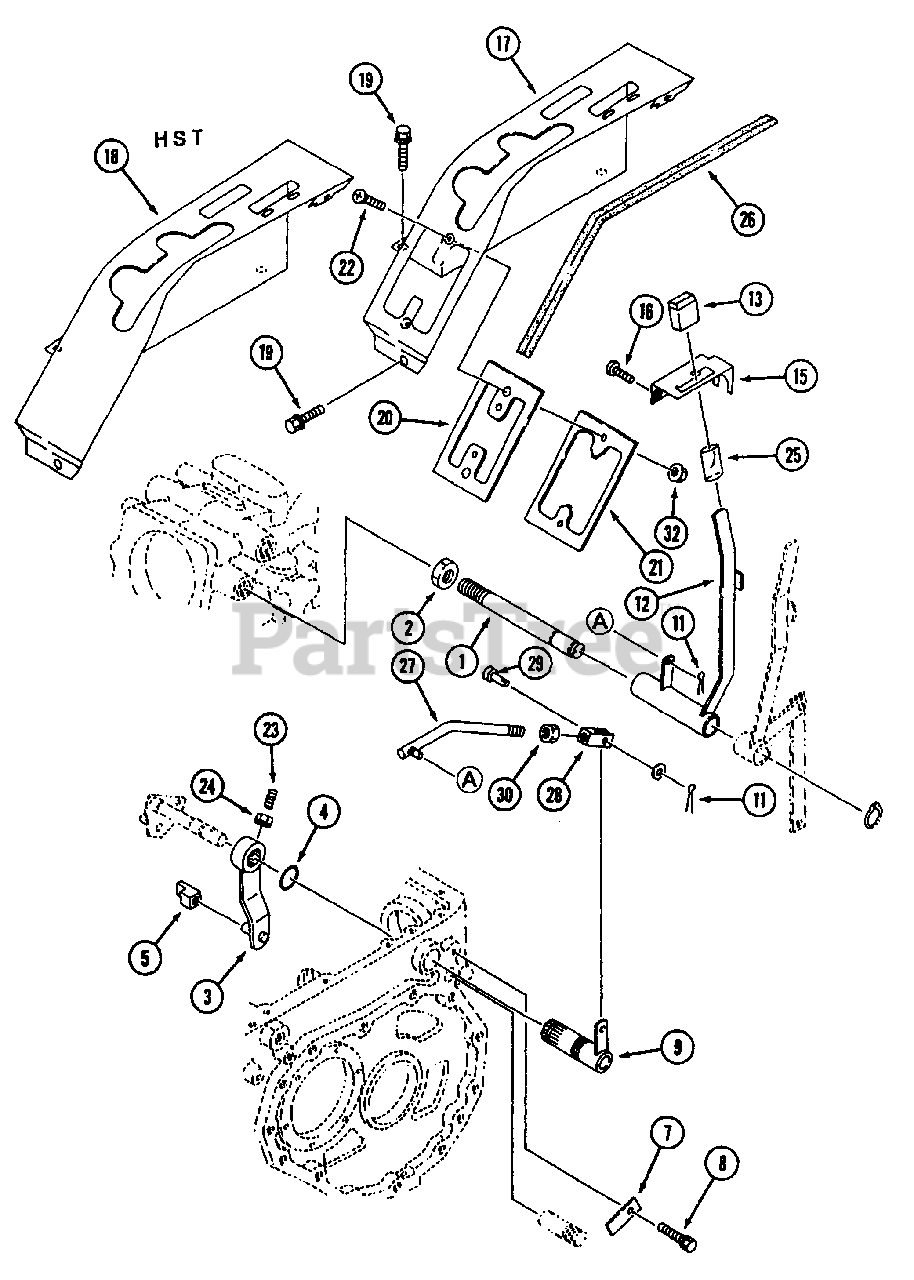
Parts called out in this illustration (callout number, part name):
1	Shaft,PTO Lever
3	Shifter,R PTO
9	Arm, Rear PTO
11	Pin, Split
12	Lever, Rear PTO
15	Plate, Rear PTO
17	Lever, Guide L.H.
18	Lever, Guide L.H.
20	Guide, Rubber
21	Plate
22	Screw
32	Nut
